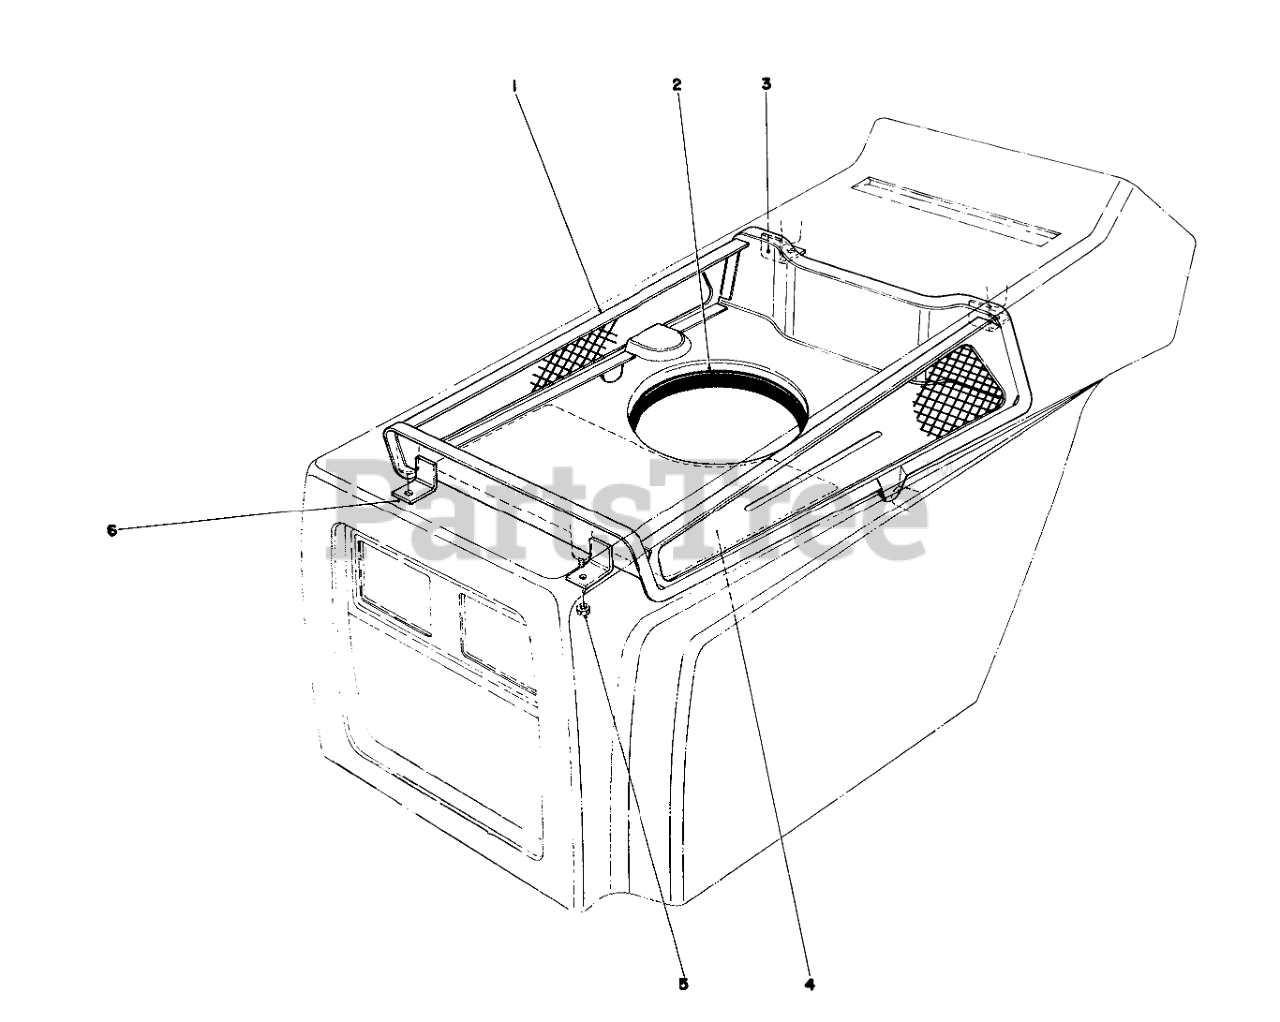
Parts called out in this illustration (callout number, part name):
1	Duct Hood
2	Seal Engine
3	Bracket Rear Duct Support
4	Decal Service
5	NUT-LOCK, NI
6	Bracket Duct Support
